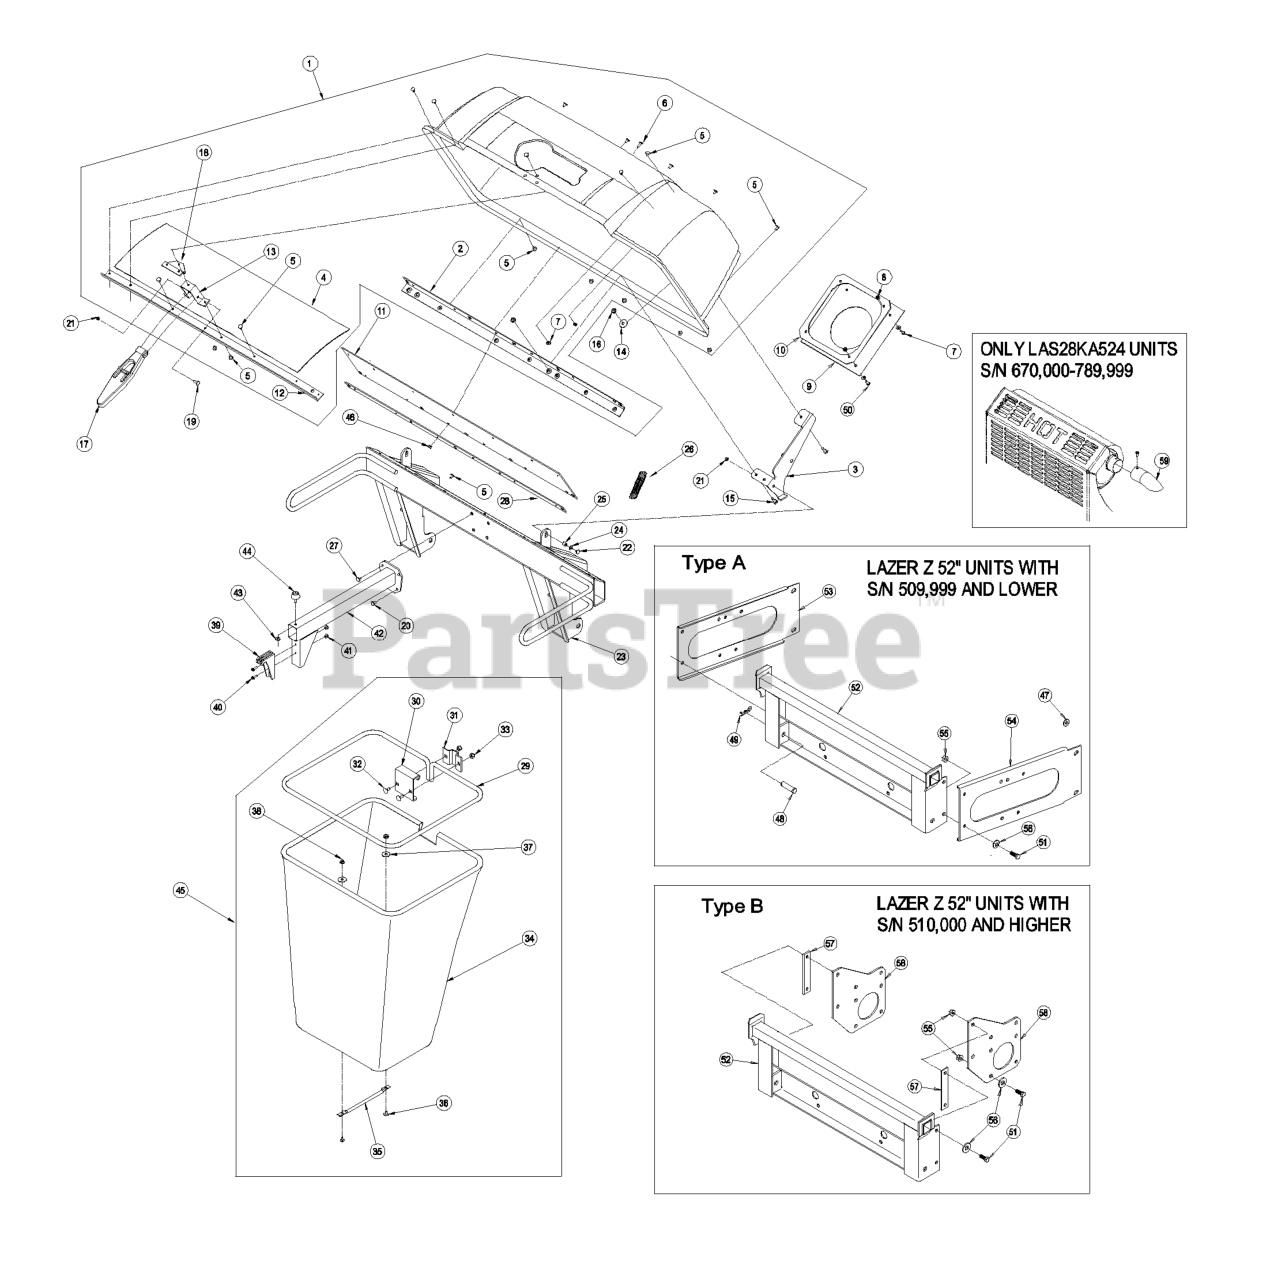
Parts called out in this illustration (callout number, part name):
1	ASM, HOOD
2	STIFFENER-BAGGER, TOP
3	HINGE-RH
4	SCREEN-BAGGER
5	RIVET-BLIND
6	SCREW-HEAD, TRUSS
7	WASHER-FLAT
8	NUT-LOCK, NI
9	SEAL-CHUTE
10	CLAMP-SEAL
11	SEAL-HOOD
12	SUPPORT-SCREEN
13	ANCHOR-LATCH
15	SCREW-HH
18	REINFORCEMENT-LATCH
19	SCREW-HH
20	SCREW-HSBH
21	NUT-LOCK, NI
22	SCREW-HH
23	UPRIGHT-BAGGER
24	WASHER-FLAT
26	SPRING-EXTENSION
27	SCREW-HH
28	PLATE-BACKING
29	FRAME-BAG
30	HANGER-BAG
32	BOLT-CARR
33	NUT-LOCK, NI
35	HANDLE-BAG
36	BOLT-CARR
38	NUT-LOCK, NI
40	SCREW-PPH
42	SUPPORT-BAG
46	NUT-LOCK, SIDE
47	SPACER
48	PIN-CLEVIS
49	PIN-COTTER
50	SCREW-PPH
51	SCREW-HH
52	MOUNT-BAGGER
53	BRACKET-FRAME, LH
54	BRACKET-FRAME, RH
55	NUT-HHF, WHIZ
56	WASHER-BELLEVILLE
57	SPACER
58	PLATE-MOUNT, BAGGER
59	TUBE,EXHAUST DEFLECTOR
